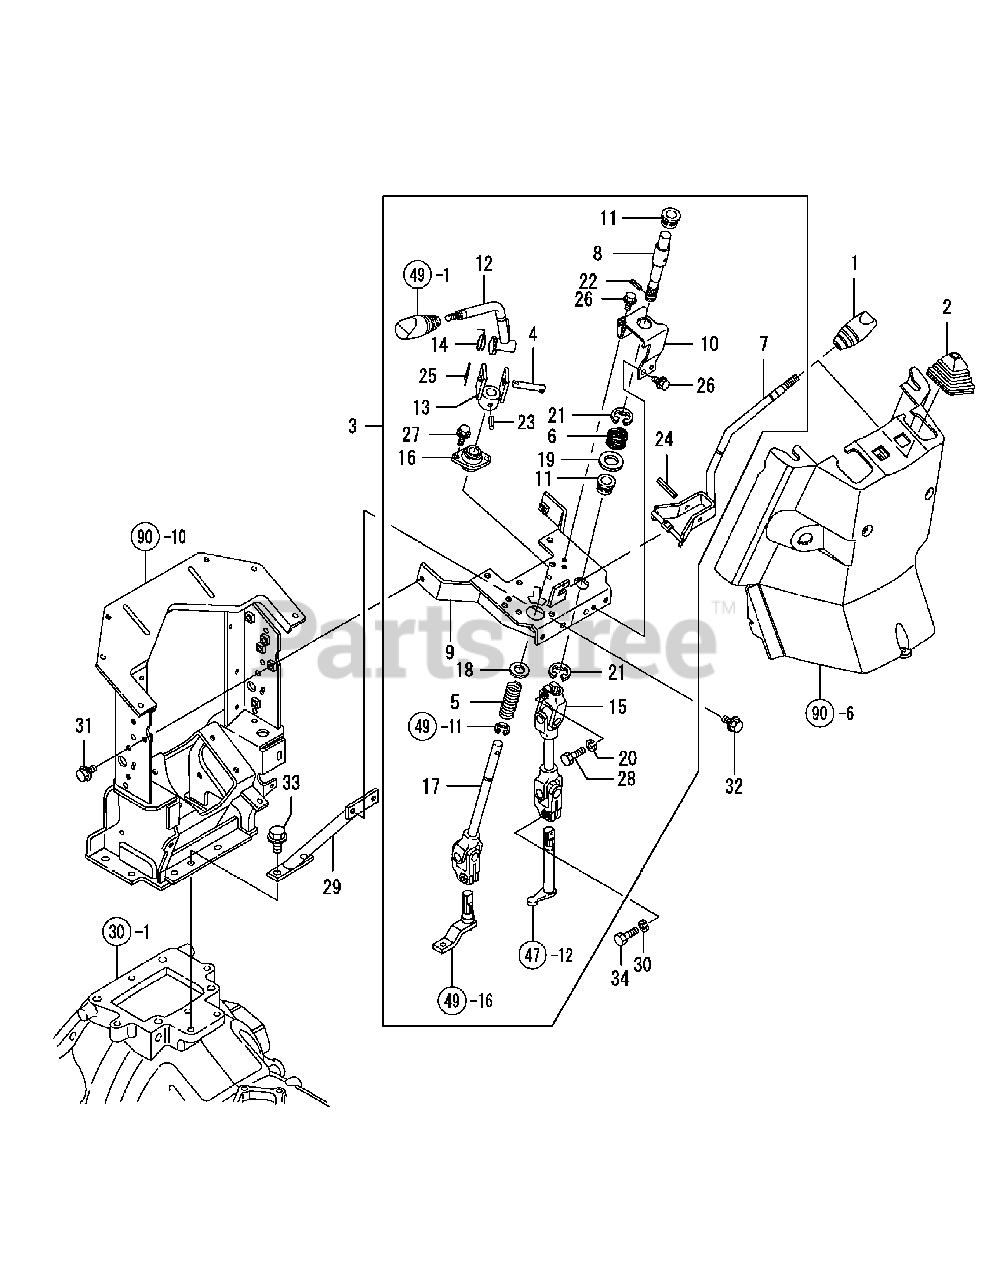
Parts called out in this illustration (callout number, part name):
1	KNOB, MAIN SHIFT
3	SHIFT ASSY, COLUMN
5	SPRING,REVERSER
7	LEVER,MAIN SHIFT
8	SHAFT,MAIN CHANGE
9	BRACKET,COLUMN SHIFT
10	STAY,MAIN CHANGE
12	LEVER,REVERSER
13	HOLDER,REVERSER
14	SPRING,REVERSR.RETRN
15	JOINT MAIN CHG
16	FLANGE UNIT,REVERSER
17	SHAFT,REVERSER COMP.
18	WASHER 14,POLISHED
22	SPRING PIN 2X 12
23	SPRING PIN 6X32
24	SPRING PIN 8X40
25	COTTER PIN 2.0X30
26	BOLT M 6X 16 PLATED
27	BOLT M 6X 16 PLATED
28	BOLT M 8X 25 PLATED
29	STAY,CLM.SHIFT COMP.
31	BOLT M 8X 16 PLATED
32	BOLT M 8X 16 PLATED
33	BOLT M10X 20 PLATED
34	BOLT M 8X 25 PLATED
